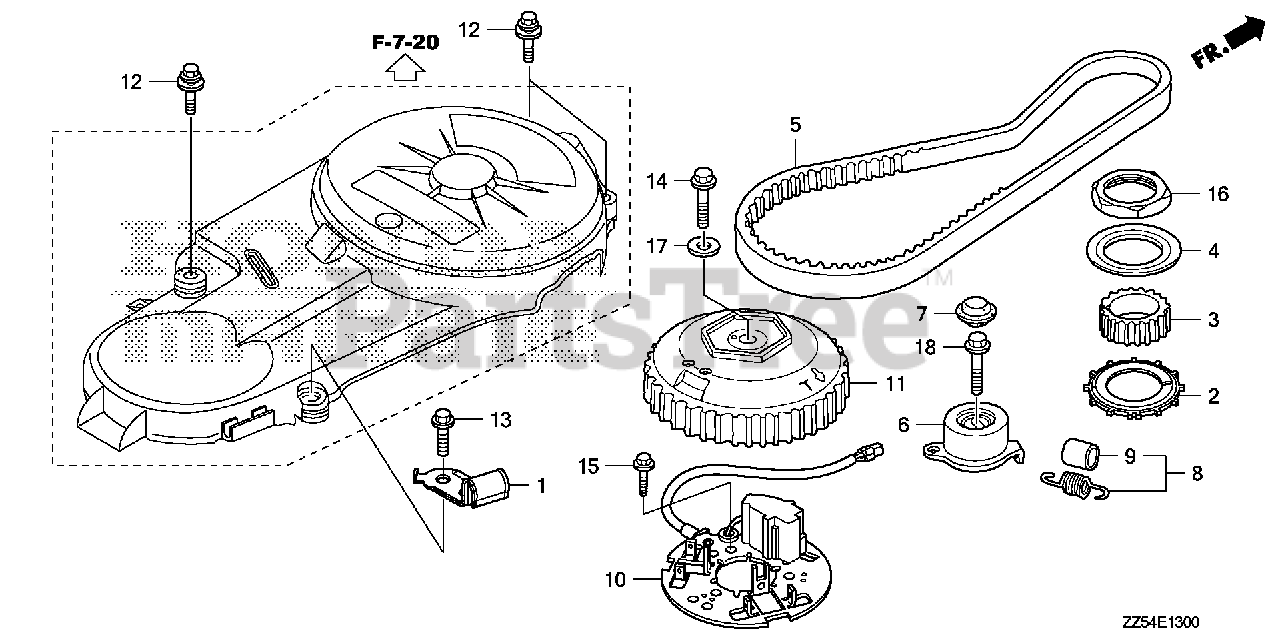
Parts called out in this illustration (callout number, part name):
1	CLAMP, TUBE
2	PLATE, TIMING BELT GUIDE
3	PULLEY, TIMING (22T)
4	PLATE, TIMING BELT GUIDE
5	BELT, TIMING
6	TENSIONER, TIMING BELT
7	CAP, TIMING BELT TENSIONER
8	SPRING, TIMING BELT ADJUSTING
9	BOOT, SPRING
10	COIL ASSY., PULSER
11	ROTOR, PULSER (44T)
12	BOLT-WASHER (6X25)
13	BOLT, FLANGE (6X25)
14	BOLT, FLANGE (10X32)
15	BOLT, FLANGE (6X12)
16	NUT, LOCK (48MM)
17	WASHER (10X28X5)
18	BOLT, FLANGE (10X38)
